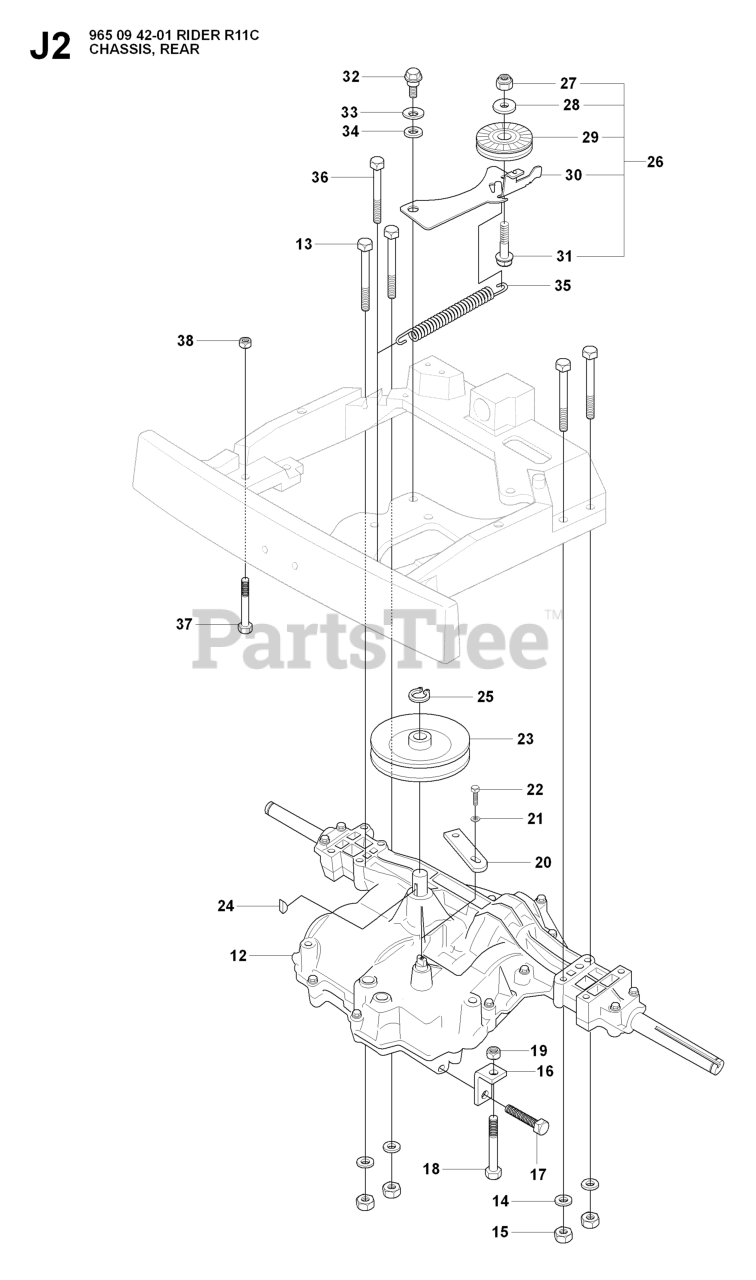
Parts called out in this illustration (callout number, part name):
14	WASHER BRB 8.4X17
15	NUT
16	Wire Bracket
18	SCREW
19	NUT
21	WASHER
25	Retaining Ring Sga 16
27	LOCKNUT M8
31	SCREW
33	SPRINGWASHER
34	WASHER - M12
35	SPRING
37	SCREW
38	NUT
